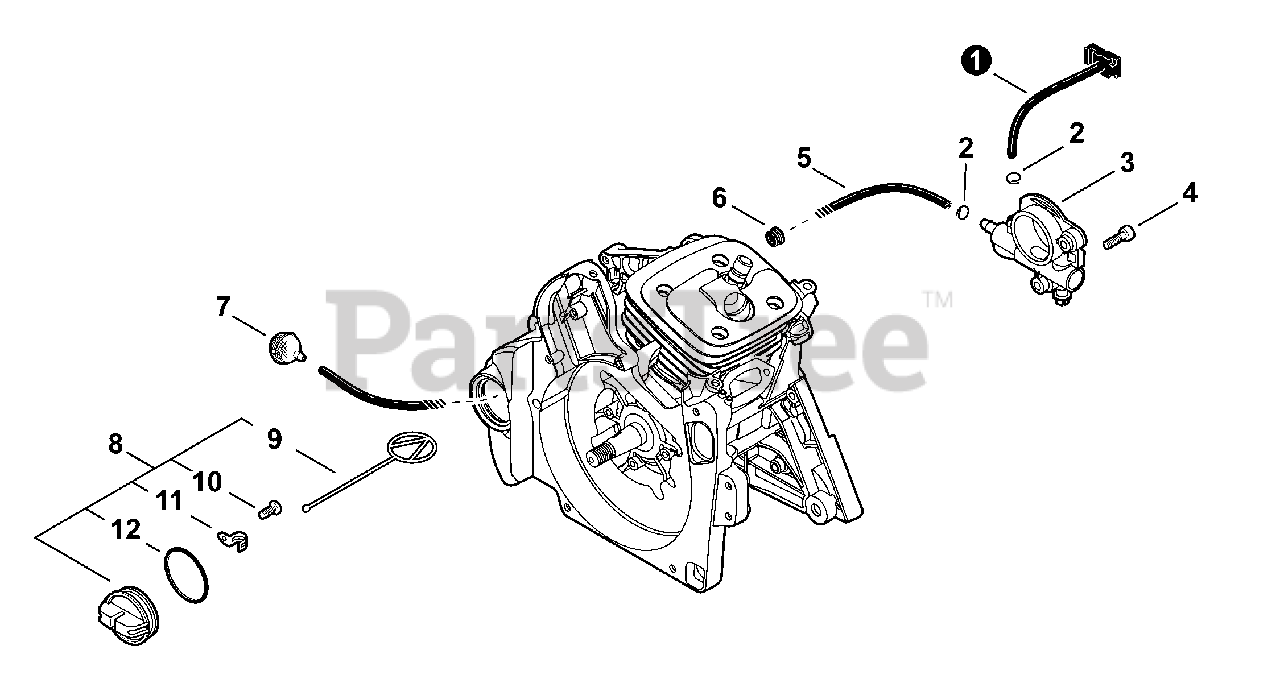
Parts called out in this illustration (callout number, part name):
1	PIPE, OIL
2	CLIP Ø6
3	AUTO-OILER ASSY
4	BOLT, TORX 4×12
5	PIPE, FUEL 3×6×210 BLACK
6	GROMMET
7	FILTER, OIL
8	CAP ASSY, OIL
9	CONNECTOR, CAP L= 60 MM
10	SCREW, TAPPING 3×8
11	RETAINER, CONNECTOR
12	O-RING 28
